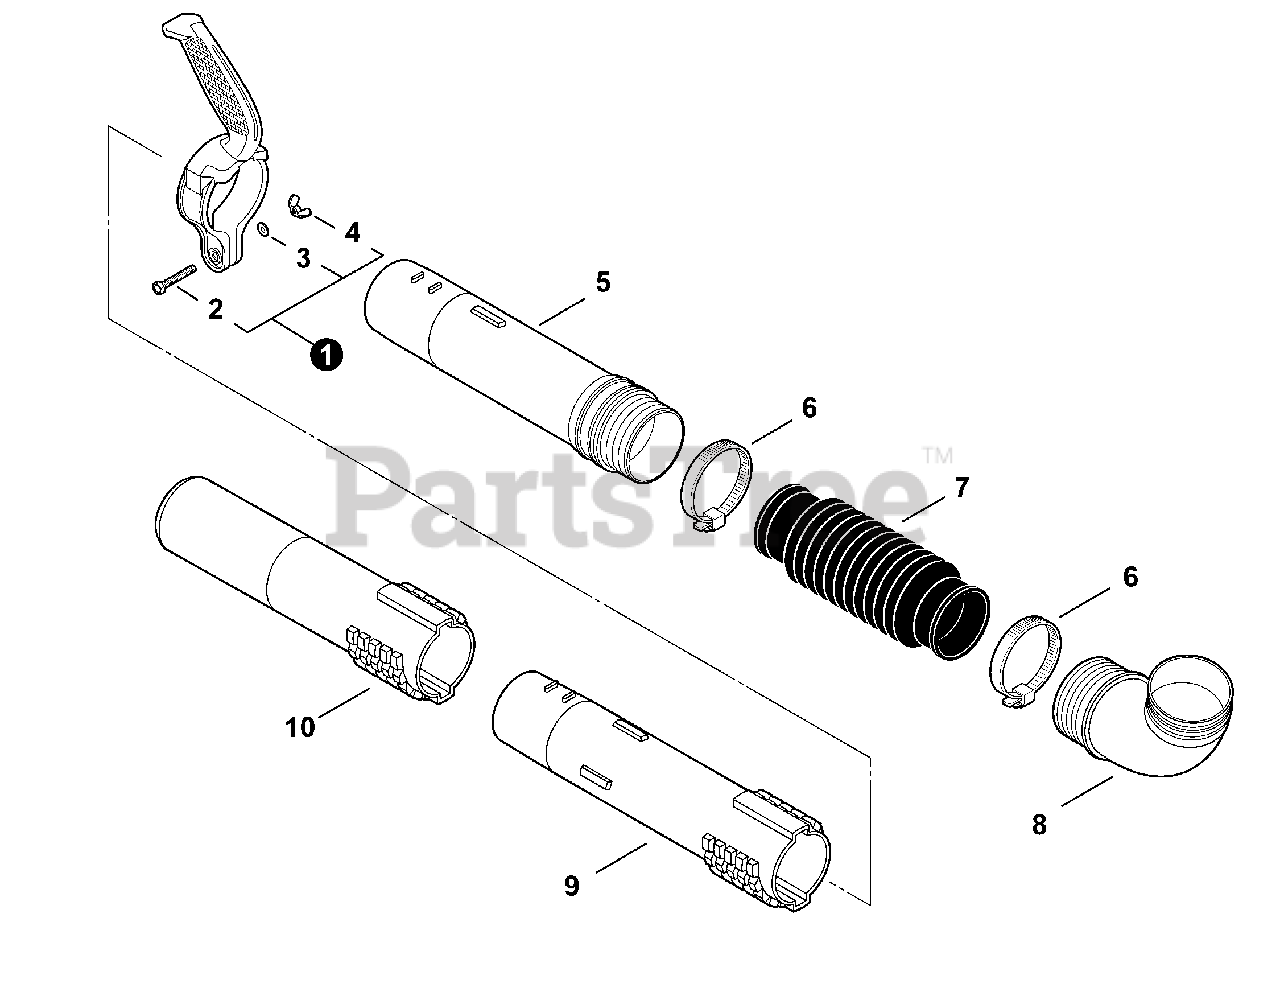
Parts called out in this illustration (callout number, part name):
1	HANDLE ASSY, PB LARGE
2	BOLT 6×45
3	WASHER 6.5×11.5×0.8
4	NUT, WING 6
5	TUBE, BLOWER - SWIVEL
6	CLAMP 58.7MM / 82.5MM
7	TUBE, BLOWER - FLEXIBLE
8	TUBE, ELBOW
9	TUBE, BLOWER - STRAIGHT
10	TUBE, BLOWER - ROUND NOZZLE
